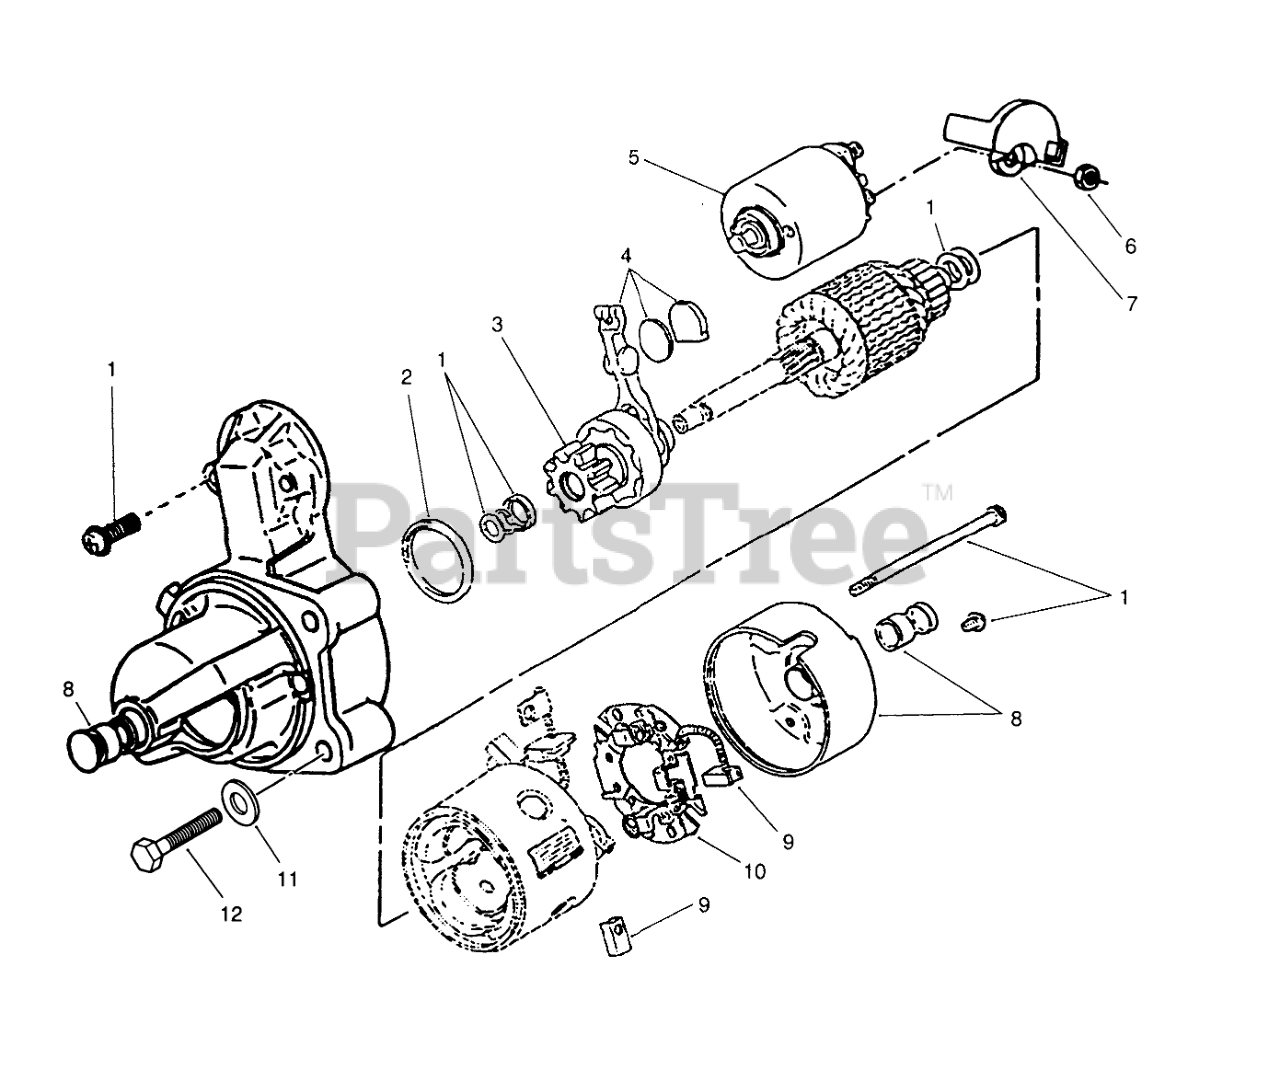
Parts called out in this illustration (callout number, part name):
1	Kit-Hardware, Starter (Incl. Solenoid Screws, Brush Holder Screws, Thru Bolts, Shims, Pinion Stop Collar, & Pinion Retaining Rings)
2	DUST-SEAL KIT
3	Kit-Clutch, Starter
4	LEVER
5	Solenoid-Starte
6	Nut-Hex.
7	Cap-Starter Solenoid
8	Kit-Bushing, Starter (Incl. Rear Cap, Front & Rear Bushings)
9	Kit-Brush, Starter (Incl. Item #10)
10	Holder-Brush, Starter
11	Washer
12	Screw-Hex Hd
13	KIT-MTG BRKT
14	WASHER
